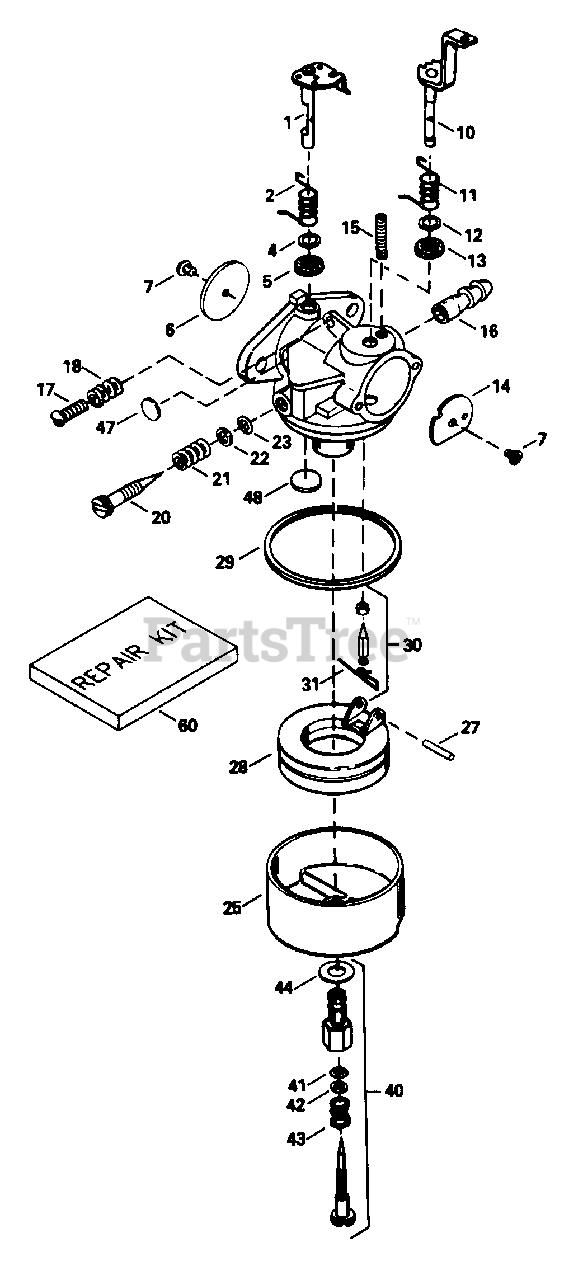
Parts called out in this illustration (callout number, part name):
1	Throttle Shaft & Lever Ass'y.
2	Throttle Return Spring
4	Dust Seal Washer
5	Dust Seal (Throttle)
6	Throttle Shutter
7	Throttle & Choke Shutter Screw
10	Choke Shaft & Lever Ass'y.
11	Choke Return Spring
12	Dust Seal Washer (Choke)
13	Dust Seal (Choke)
14	Choke Shutter
15	Choke Positioning Spring
16	Fuel Fitting
17	Idle Speed Screw
18	Tension Spring
20	Idle Mixture Screw
21	Idle Tension Spring
22	Washer, Idle Screw
25	Float Bowl
27	Shaft, Float
28	Float
29	O-Ring, Float Bowl to Body
30	Inlet Needle, Seat & Spring Clip
31	Spring Clip
40	Adjustment Screw Ass'y., Main
41	O-Ring, High Speed Mixture Screw
42	Washer, High Speed Mixture Screw
43	Tension Spring, High Speed Mixture Screw
44	Bowl Nut Washer
47	Welch Plug, Idle Mixture Well
48	Welch Plug, Atmospheric Vent
60	Repair Kit
